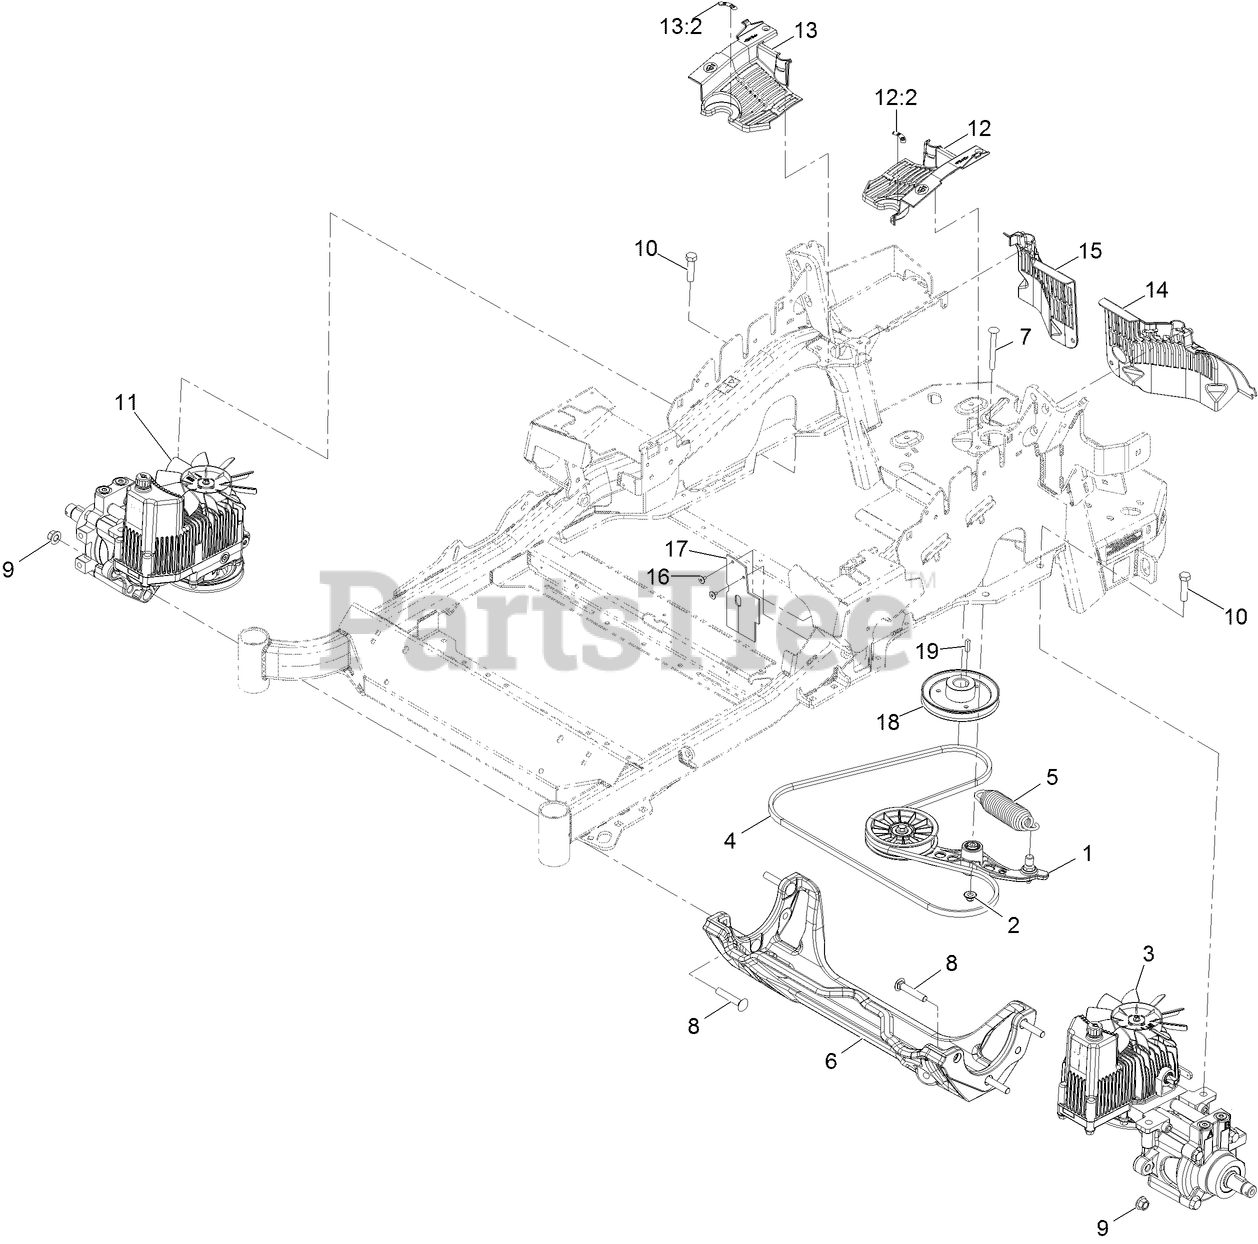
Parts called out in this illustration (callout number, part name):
1	PUMP IDLER ASM
2	Nut-Nyloc 3/8-16 Flg
3	HYDRO-LH
5	SPRING-EXTENSION
6	CRADLE-HYDRO
7	BOLT-SHOULDER, CARRIAGE 3/8-16 X 3 1/2
8	SCREW-CARR
9	Nut-Lock 1/2-13
10	SCREW-HH
11	HYDRO-RH
12	LH HYDRO GUARD ASM
12:2	DECAL-OIL, HYDRO
13	RH HYDRO GUARD ASM
13:2	DECAL-OIL, HYDRO
14	GUARD-HYDRO, REAR (LH)
15	GUARD-HYDRO, REAR (RH)
16	RIVET-POP
17	DEFLECTOR-AIR FLOW
18	SHEAVE
